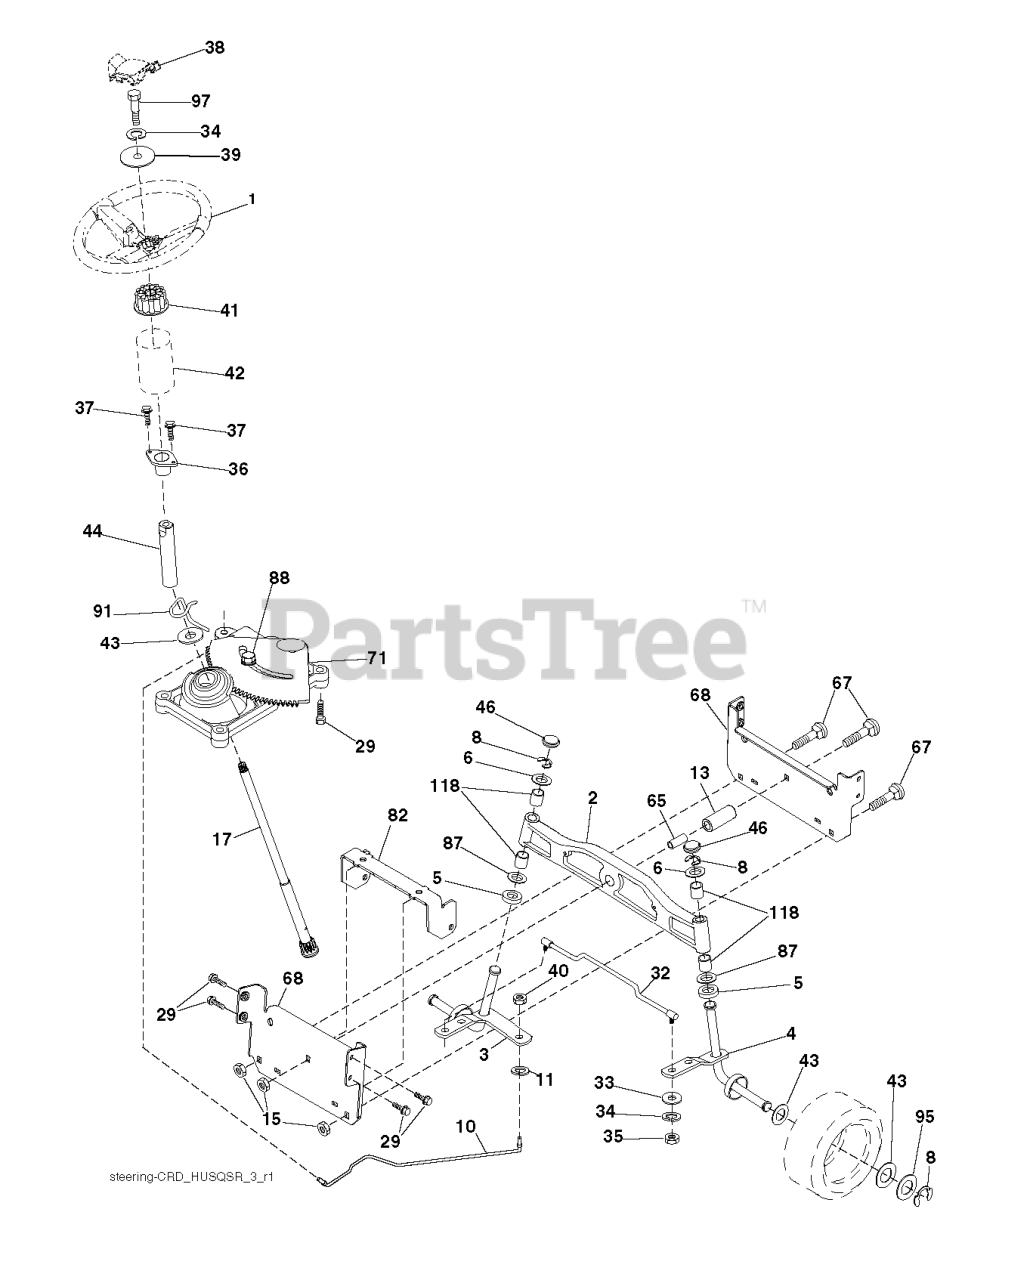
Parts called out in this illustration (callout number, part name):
1	WHEEL.STEER.HUSQ.SR.498.OVMLD
2	AXLE.ASM.LT.CAST.LGHTWGHT
3	SPINDLE.ASM.LH.15"TIRES
4	SPINDLE.ASM.RH.15"TIRES
5	THRUST WASHER
10	DRAGLINK.15".TIRES.2001
11	WASHER, LOCK 3/8
13	TUBE, PIVOT AXLE
15	NUT LOCK FLG 3/8-16 UNC
17	SHAFT STEERING SPLINE
29	SCREW, 3/8-16X3/4
33	WASHER M
34	WASHER.LOCK.HVY.HLCL.SPR.5/16
35	NUT, CROWNLOCK
36	BUSHING, STEERING
37	SCREW.TT.#10-32X.5.3/8.FLANGE
38	INSERT.CAP.WHL.STRG.HUSQ.PREM
39	WASHER.11/32
40	NUT CROWNLOCK 3/8-24
41	ADAPTER, WHEEL STNG..
42	STEERING.BOOT.HUSQ.LT
44	SHAFT.EXTEN.STRG.SPLINE
46	CAP.SPINDLE.BLACK
65	SPACER.BRACE.AXLE
67	BOLT CARRIAGE
68	BRACE.AXLE.15"TIRES
71	STEERING ASM
82	BRACKET.SUSP.CHASSIS.FRONT.15
87	WASHER, FLAT .781 X 1 1/2"
88	BOLT, SHOULDER 7/16-20
91	CLIP.STEERING
95	WASHER.HARDENED
97	BOLT 5/16-18 X 4 W/PATCH
118	BUSHING, AXLE CAST
